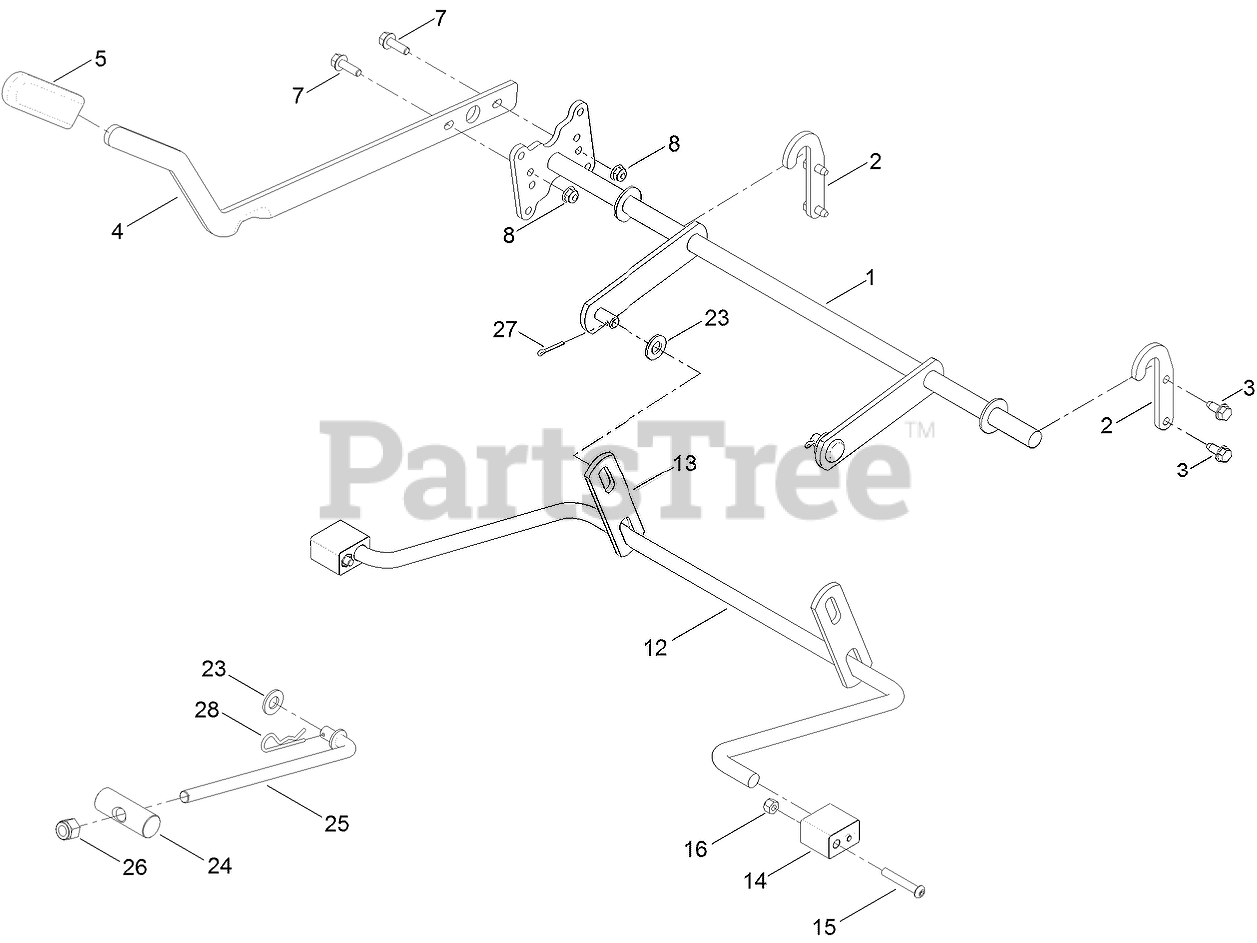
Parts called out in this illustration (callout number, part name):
1	LIFT-DECK, WIDE
2	BRACKET-LIFT
3	SCREW-HWHTF
4	LEVER-LIFT
5	GRIP-LEVER
7	SCREW-HHF
8	NUT-HF, NI
12	ARM-LIFT, REAR (WIDE)
13	LINK-LIFT
14	BLOCK-PIVOT
15	SCREW-HSBH
16	NUT-LOCK, NI
23	WASHER-FLAT
24	PIN-PIVOT
25	ROD-MOUNT, DECK
26	NUT-HEX
27	PIN-COTTER
28	PIN-COTTER
